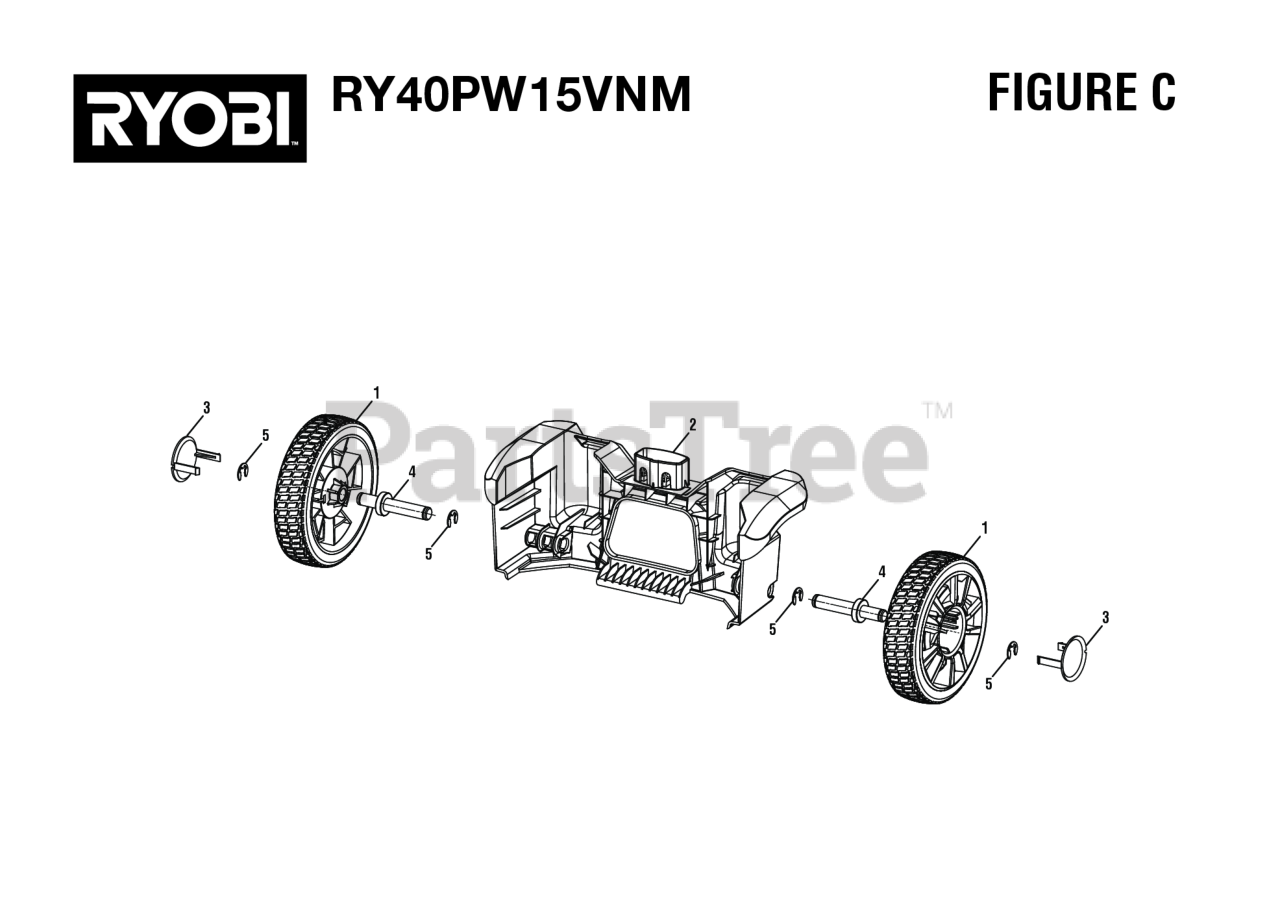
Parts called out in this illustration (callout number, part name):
2	Wheel Base Bracket
3	Wheel Cover
4	Wheel Axle
5	Retaining Ring
